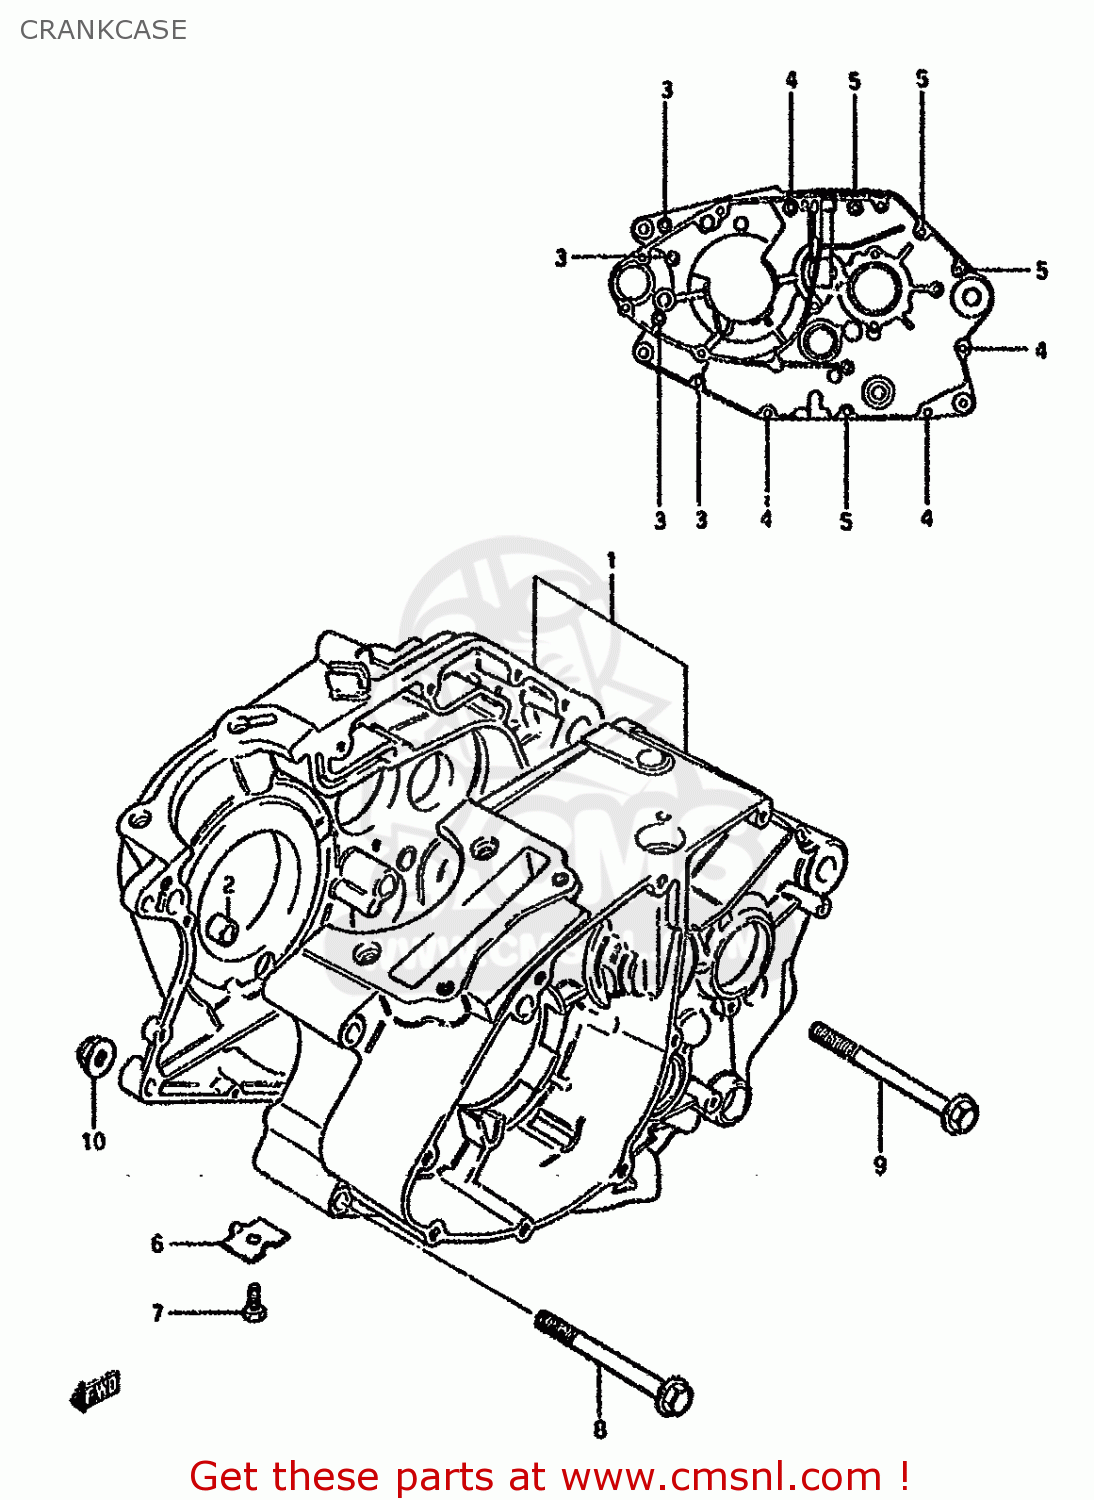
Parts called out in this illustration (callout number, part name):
1	CRANKCASE SET
2	PIN
3	BOLT
4	BOLT
5	BOLT
6	PLATE,OIL GALLERY PLUG
7	BOLT
8	BOLT(8X80)
9	BOLT(8X88)
10	NUT
